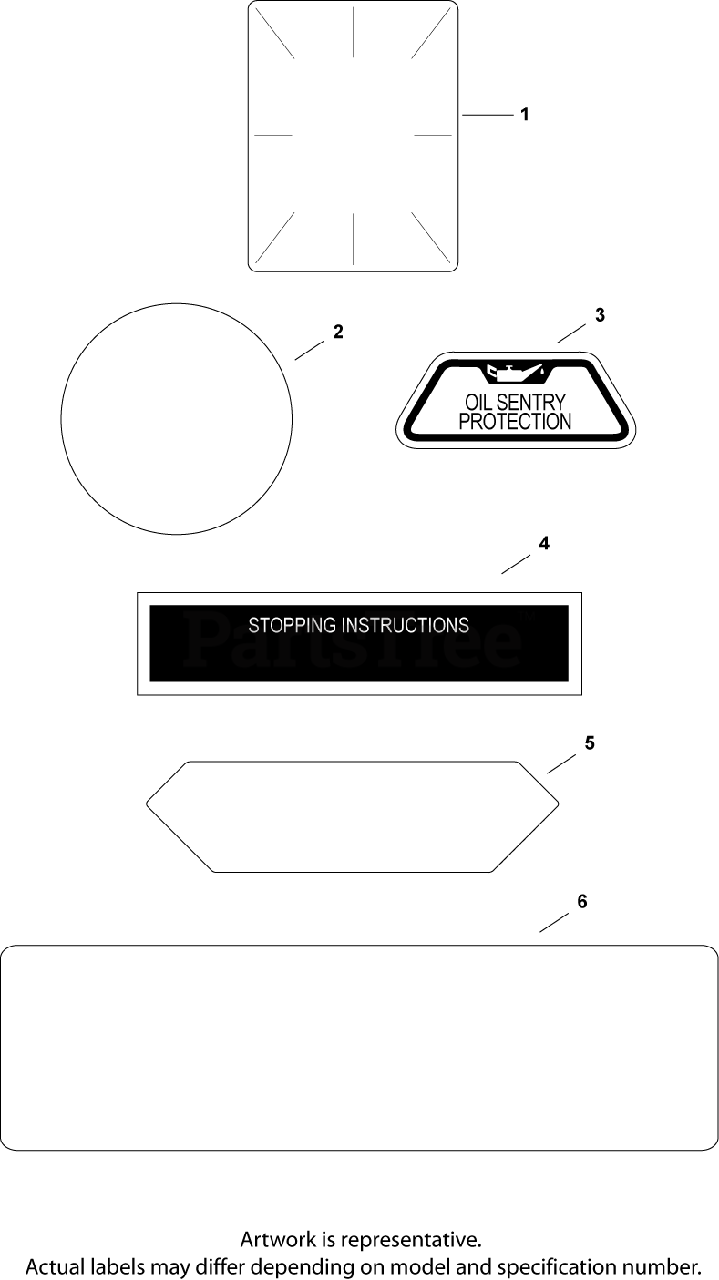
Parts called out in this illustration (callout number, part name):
1	DECAL, CLEAR LAMINATE USE 25 113 70-S
2	DECAL, GRASS SCREEN USE 24 113 499-S
3	DECAL, OIL SENTRY - (#DSC)
4	DECAL, STOPPING INSTRUCTION
5	DECAL, AIR FILTER COVER - DISC.
6	DECAL, 18 HP
